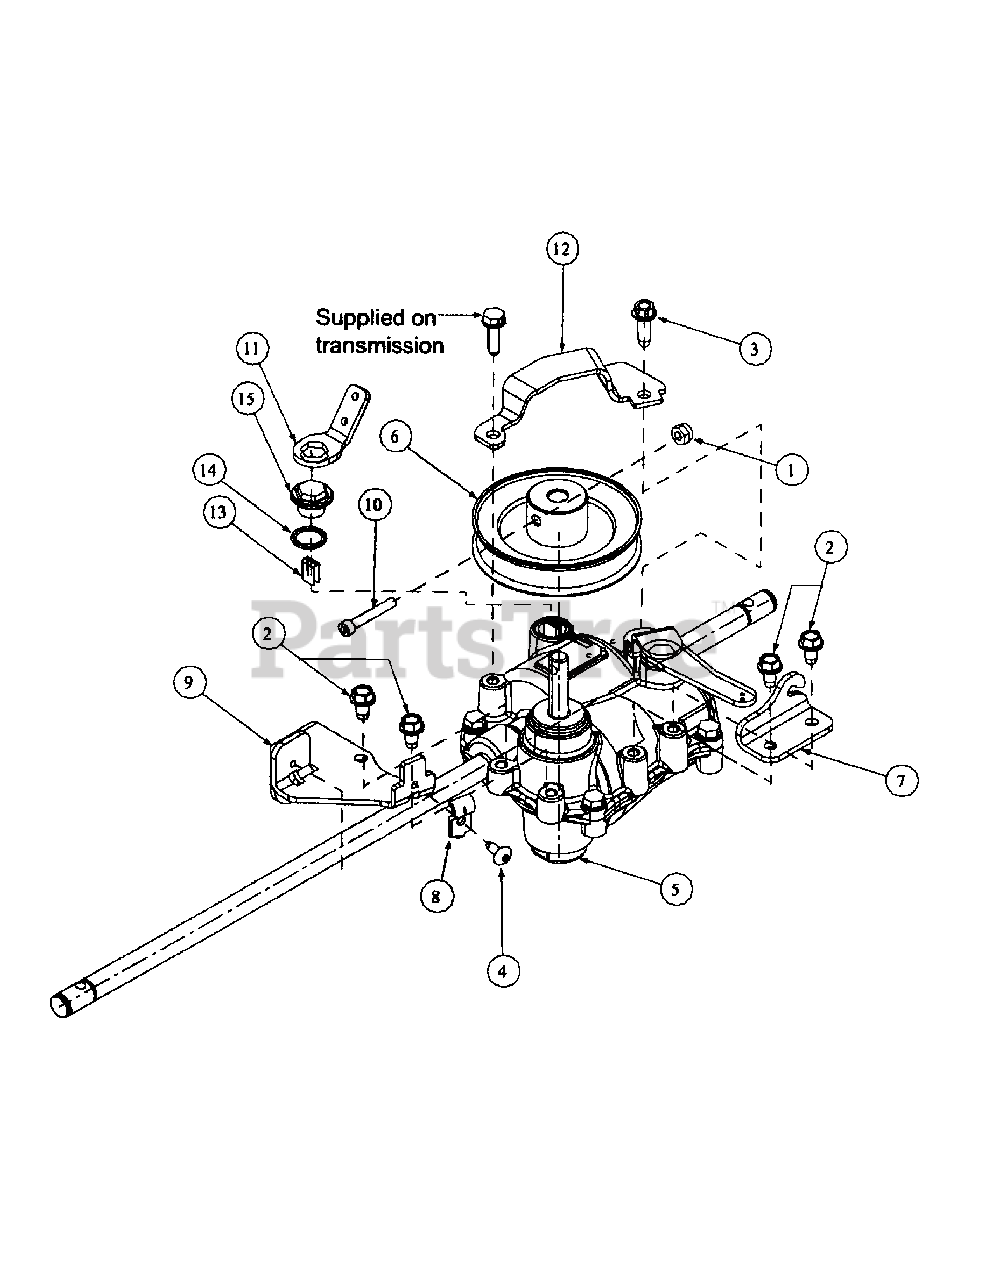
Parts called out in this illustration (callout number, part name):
1	Nylon Lock Nut, #10-24
2	Screw, TT, Hex Index Washer, 1/4-20, 0.500
3	Screw, TT, Hex Index Washer, 1/4-20, 0.750
4	Screw, B, #10-16, 0.500, Trustrxi
5	Complete Transmission, 3-Speed
6	Transmission Pulley, 3/8V x 3.50 OD
7	Spring Bracket Transmission
8	Cable Clamp, 3/16
9	Transmission Clutch Bracket
10	Socket Screw, 10-24 x 1.25
11	Shift Bracket
12	Shift Bracket Retainer
13	Self Propelled, Shim, 21"
14	3-Speed, O-Ring, Seal
15	3-Speed, Clutch, Cap
